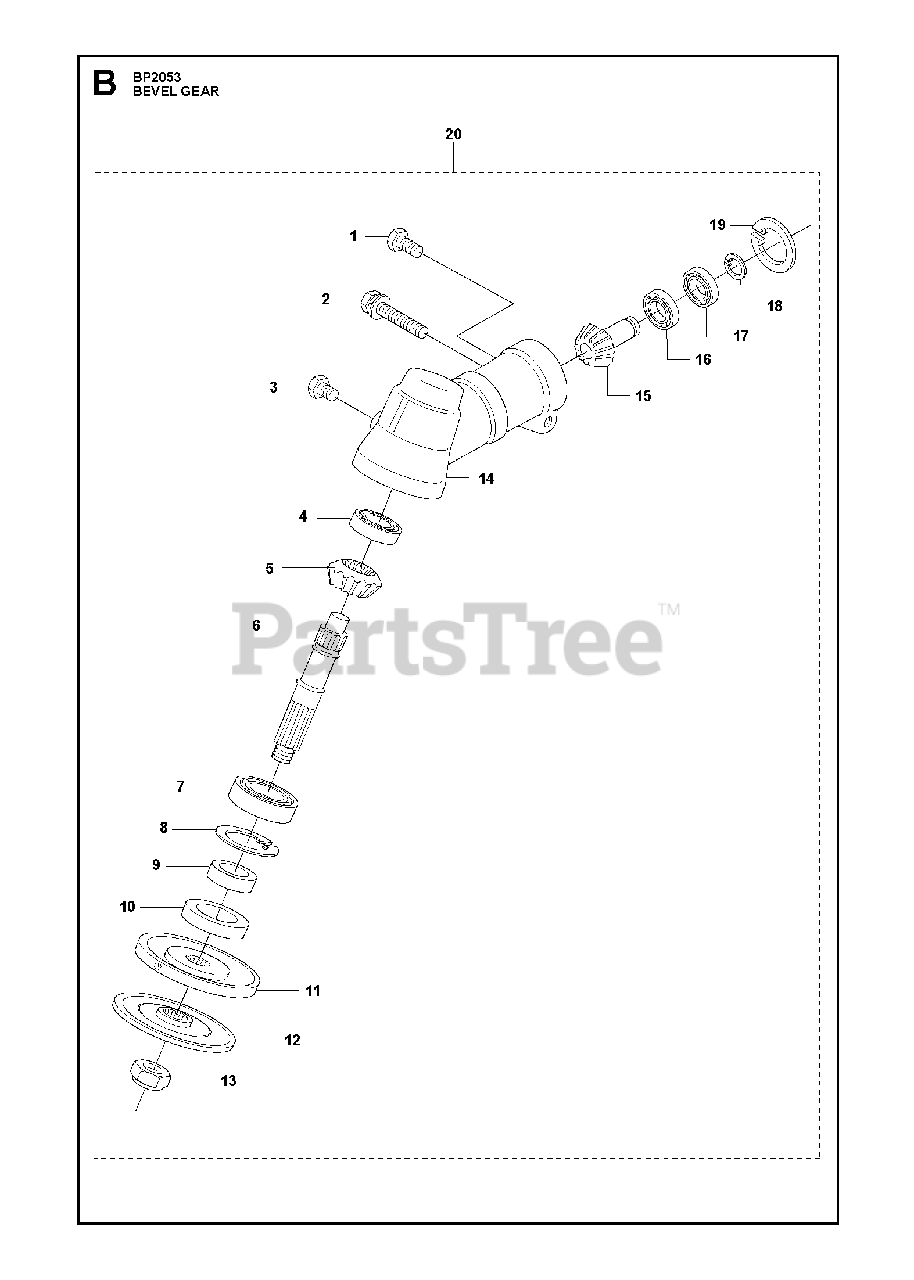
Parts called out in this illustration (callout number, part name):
1	SCREW
2	SCREW M6S 6X30
3	SCREW 8X10
4	BALL BEARING 24X9X1/609ZR
7	BALL BEARING 6002
8	RETAINING RING
9	RING
12	FLANGE
13	LOCKNUT 12X1.75
18	RETAINING RING SGA 10
19	RETAINING RING SGH 26
